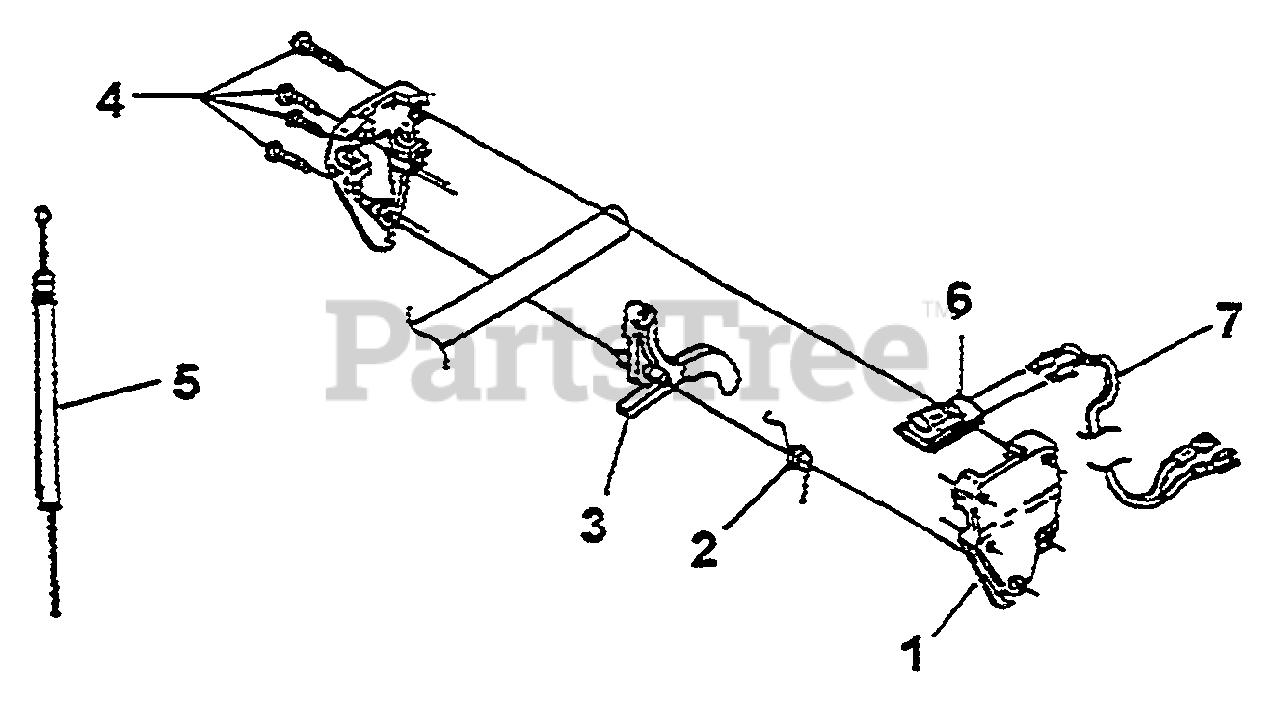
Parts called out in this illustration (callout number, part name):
1	THROTTLE ASSY.
2	SPRING, THROTTLE
3	THROTTLE
4	SCREW
5	THROTTLE CABLE
6	SWITCH ASSY
7	WIRE HARNESS
